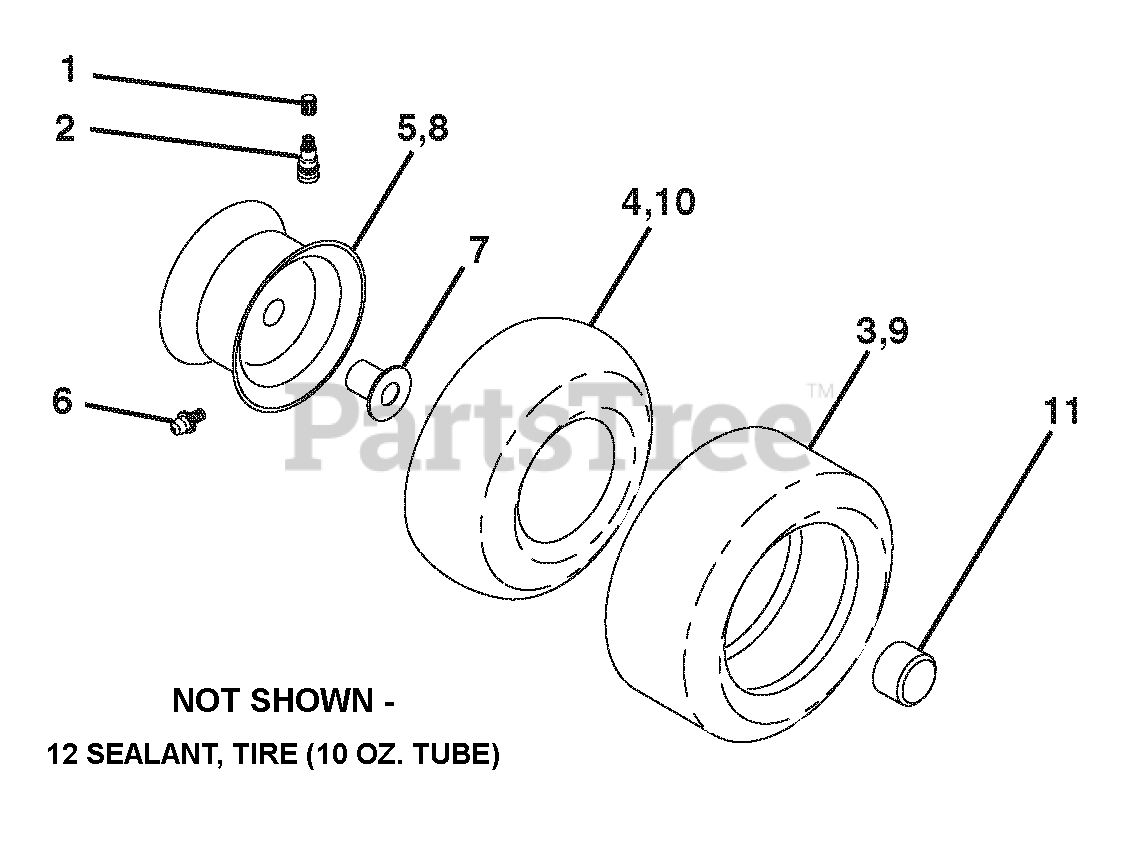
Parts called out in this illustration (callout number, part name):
1	CAP.VALVE.TIRE
2	STEM.VALVE
3	TIRE.F.TS.15 X 6.0 - 6.SERVICE
4	TUBE.INNER.FRONT.#35060
5	Rim.Asm.6"Front(w.Grey).643
6	FITTING.GREASE
7	BEARING.FLANGE
8	RIM ASM.8"REAR.BKACK.SERVICE
9	TIRE.R.TS-LT.18X9.5-8.C.SERV.
10	TUBE.REAR.9.5 X 8.SERVICE
11	CAP.HUB.AXLE.BLK.1.50 X 1.00
